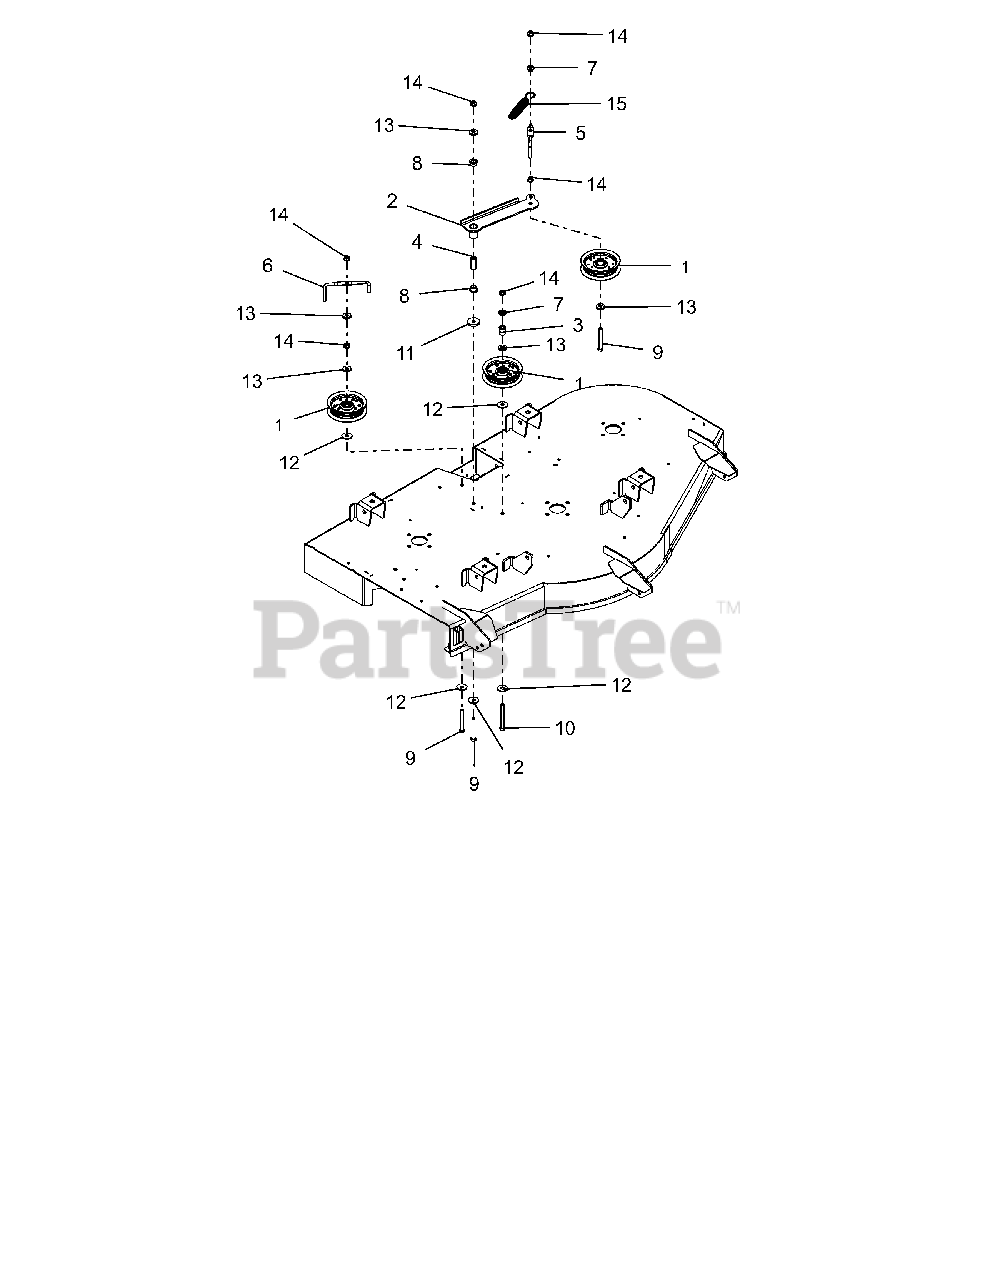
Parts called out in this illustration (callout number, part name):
1	ASM, IDLER 4"
2	WLDMT, IDLER ARM-52"
3	BUSHING, IDLER (P/M)
4	SPACER, .375IDX.625ODX1.66 PM
5	WIREFORM, BELT FINGER
6	WIREFORM, BELT FINGER
7	BSHG-FLG .385X.500X.875X.406
8	BSHG-FLG, .625X.750X.500X1.00
9	BLT-HEX .38-16X3.00 GR5 FTH YZ
10	@BLT-HEX .38-16X3.50 GR5 YWZC
11	WSHR,FLT STL.406X1.50X.245YWZC
12	WSHR FL STL .406X1.25X.10ZC120
13	WSHR-FL-STL .406X1.00X.188 YWZ
14	NUT-LK-TOP-FLG .38-16 ZC120
15	SG-TENS .135X.98X6.0 WLD 62
